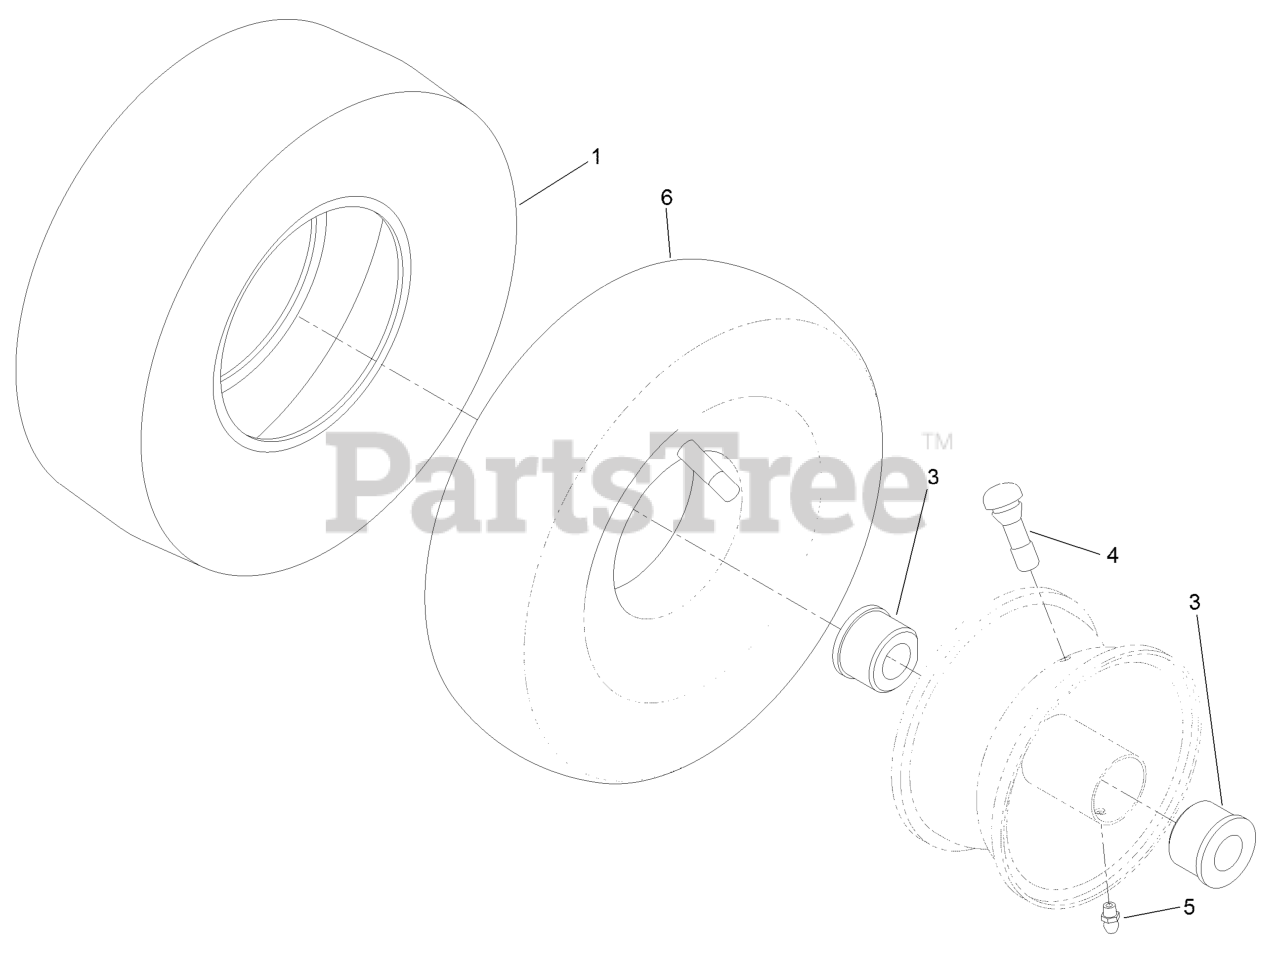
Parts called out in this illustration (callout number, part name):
3	BUSHING-FLANGE
4	Stem-Valve
5	FITTING-GREASE
6	TUBE-INNER
